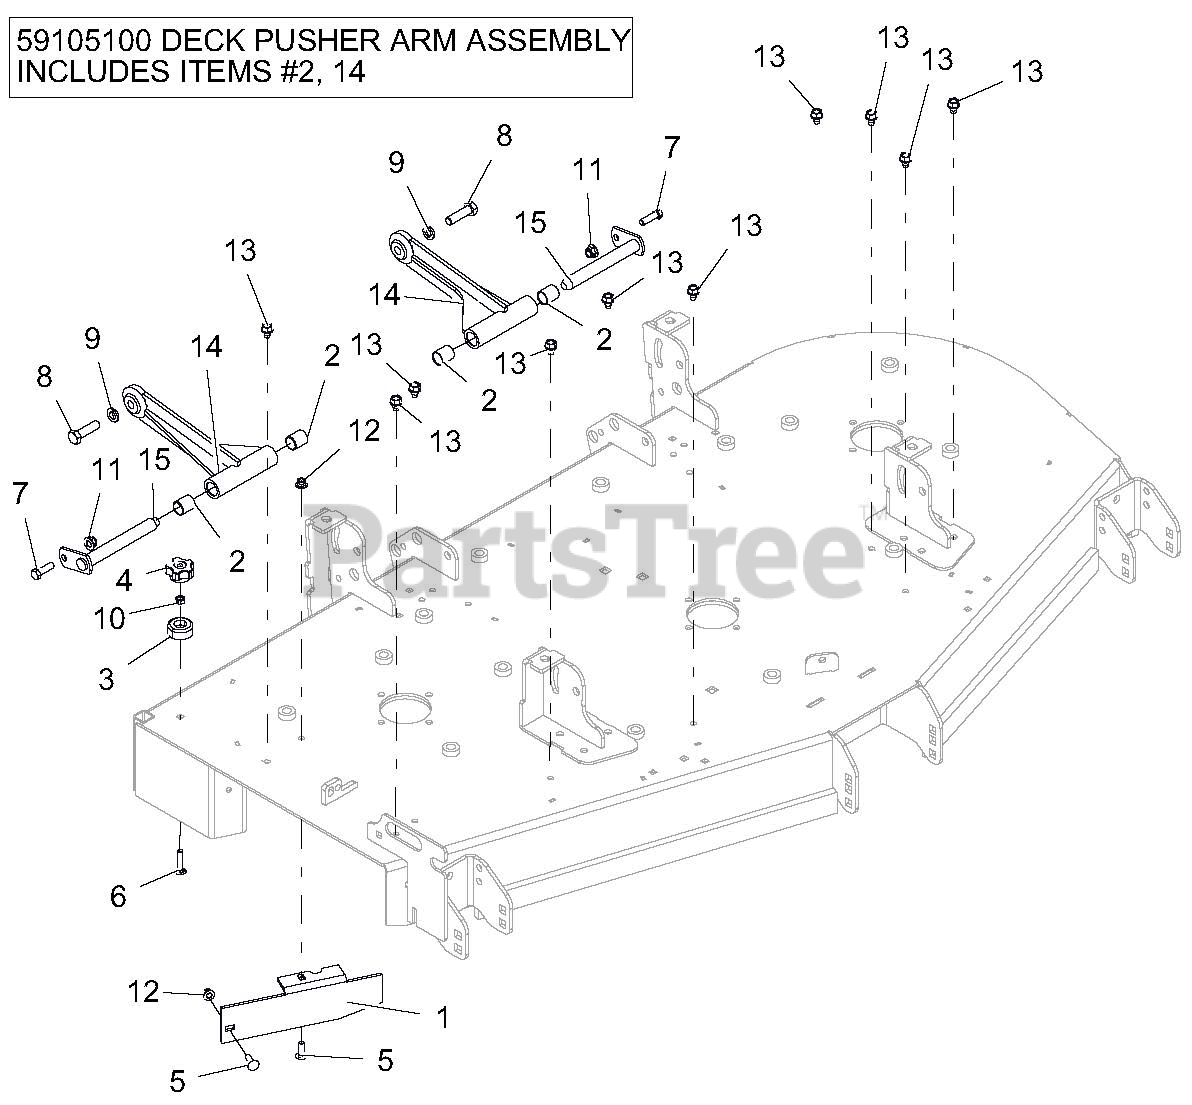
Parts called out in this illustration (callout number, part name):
1	BAFFLE, 60" DISCHARGE
2	BRG, .75 X .875 X 1.00
3	BUMPER, RECESSED 1.50 X .63 W/.31 HOLE
4	KNOB, CLAMPING
5	BLT-RDHDSQSHNK .31-18X1.00 G5 Y
6	BLT-RDHDSQNK .31-18X1.50 G5 YWZC
7	BLT-HEX .38-16X1.25 GR5 YWZC
8	BLT-HEX .50-13X1.75 GR5 YWZC EP80
9	WSHR-LK .50X.125 REG YWZC
10	NUT-LK-CTR .31-18 YWZC
11	NUT-LK-NYL-FLG .38-16 YWZC
12	NUT-LK-NYL-FLG .31-18 YWZC
13	SCR-TAP .38-16X.50 HWH TR YWZ
14	WLDMT, DECK PUSHER ARM
15	WLDMT, MOWER MTG. PIN
16	DECK PUSHER ARM ASSEMBLY
